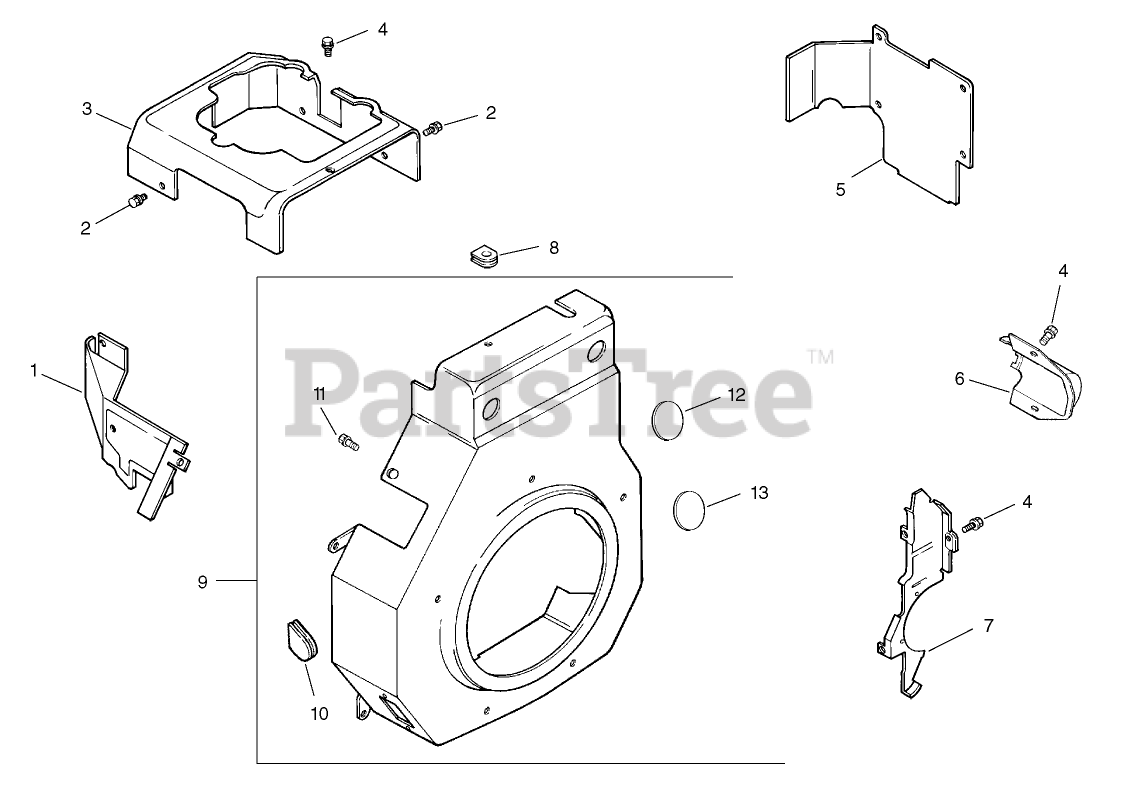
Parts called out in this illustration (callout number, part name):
1	Baffle-Side, Intake
2	SCREW-HHFTF (M5X.80X10)
3	Baffle-Head, Cylinder
4	Screw-HF (M5x0.8x10)
5	Baffle-Cylinder
6	Cover-Starter
7	Plate-Housing, Blower
8	Grommet-Spark Plug
9	Blower Housing Kit (Includes 10-13)
10	Grommet
11	SCREW-HHFTF (M5X.80X10)
12	PLUG-BUTTON (9/16)
13	Plug-Button (1/2)
